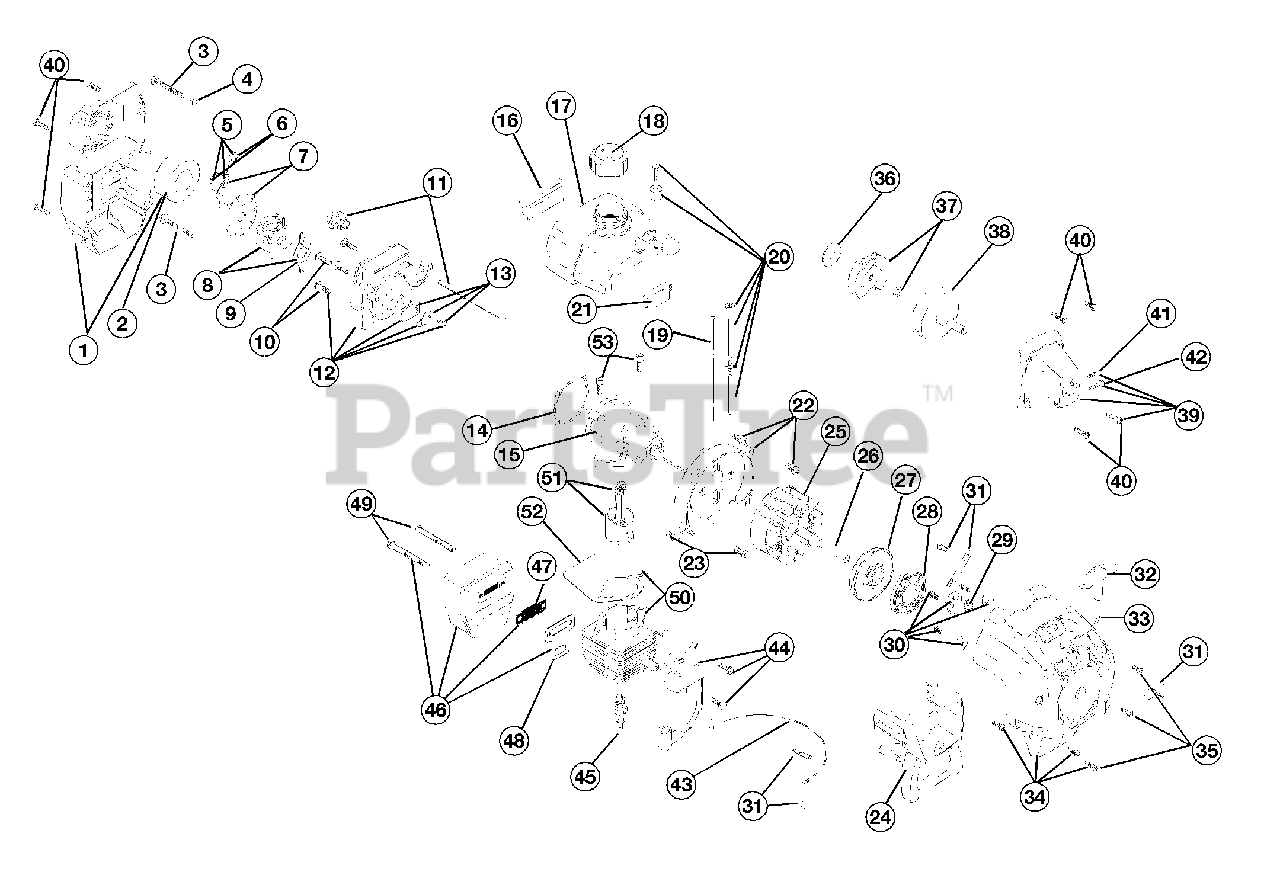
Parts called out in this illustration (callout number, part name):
1	Air Cleaner/Muffler Cover Assembly
2	Air Cleaner Filter
3	Carburetor Mounting Screw Assembly
4	Wavey Washer
5	Choke Lever Assembly
6	Choke Knob and Screw
7	Choke Lever and Plate
8	Carburetor Assembly
9	Carburetor Gasket
10	Carb Mount Screw
11	Primer and Hose Assembly
12	Carb Mount Assembly
13	Reed Assembly
14	Carburetor Mount Gasket
15	Crank Case Service Assembly
16	Rear Mounting Pad
17	Fuel Tank Assembly
18	Fuel Cap Assembly
19	Fuel Return Line
20	Fuel Line Assembly
21	Front Mounting Pad
22	Shroud Assembly
23	Shroud Screw
24	Shroud Extension and Stand
25	Flywheel Assembly
27	Recoil Pulley Assembly
28	Recoil Spring
29	Rope Guide
30	Pulley Retainer Assembly
31	Switch Assembly
32	Pull Handle
34	Starter Housing Assembly
35	Housing Screw
36	Clutch Washer
37	Clutch Rotor Assembly
38	Clutch Drum Assembly
39	Clutch Cover Assembly
40	Cover Screw
41	Anti-Rotation Screw
42	Clamping Screw
43	Wire Lead
44	Module Assembly
45	Spark Plug
46	Muffler Assembly
47	Spark Arrestor Screen
48	Exhaust Gasket
49	Muffler Mounting Bolt Assembly
50	Cylinder Assembly
51	Piston and Rod Assembly
52	Cylinder Gasket
53	Cylinder Bolt
